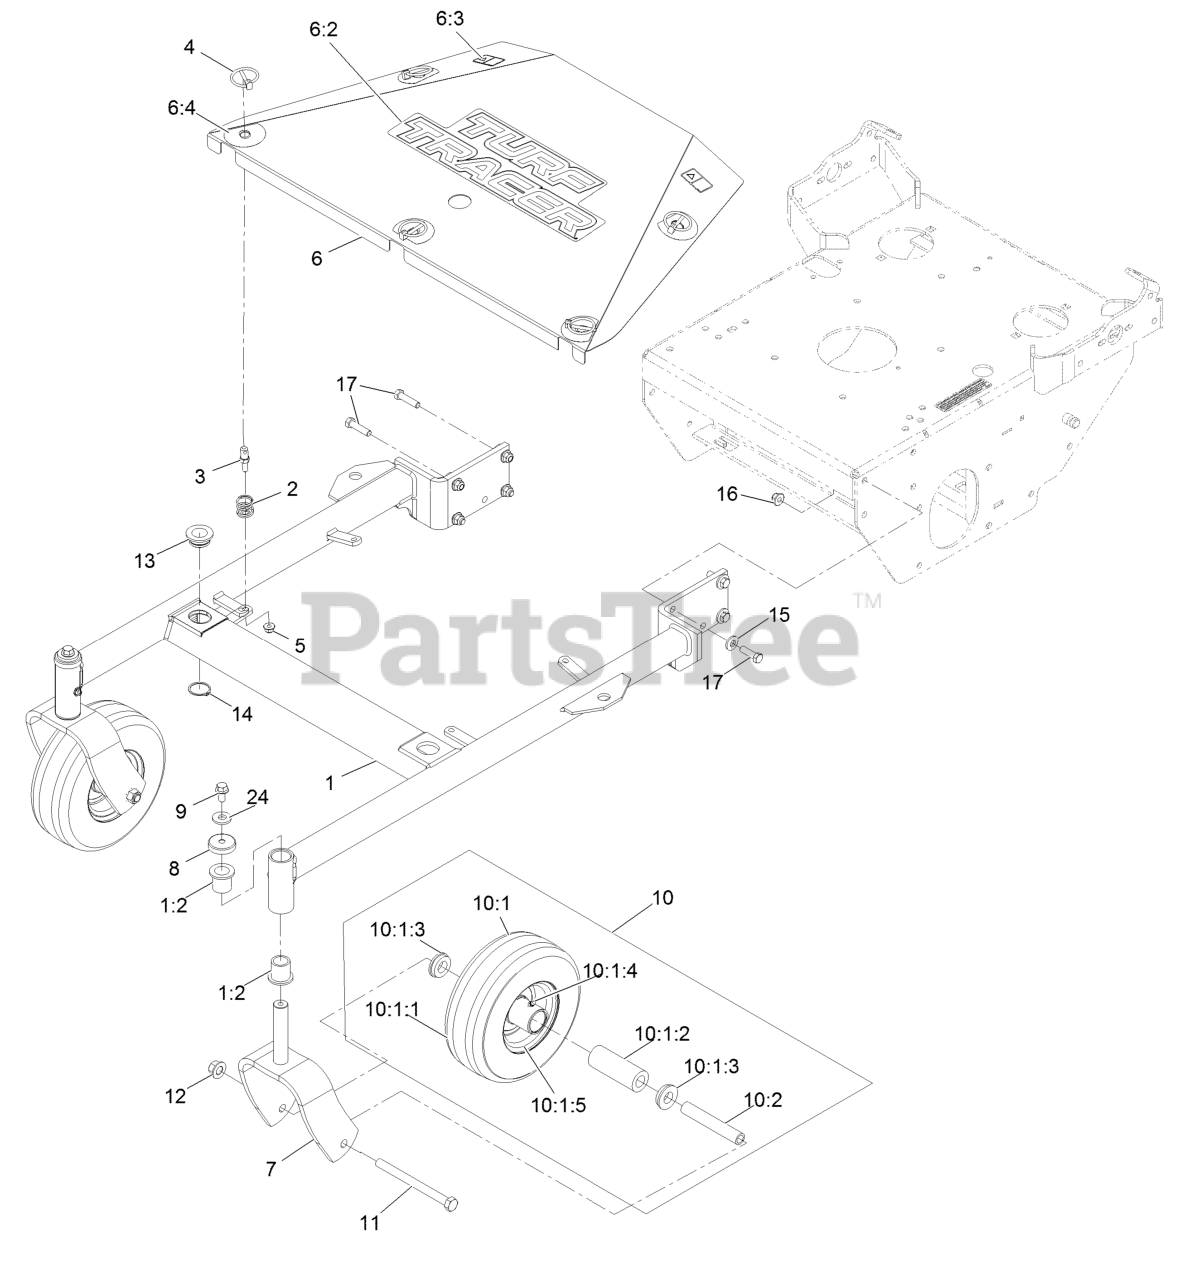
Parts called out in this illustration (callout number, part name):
1	ASM, FRAME W/ BUSHINGS, 3
1:2	BEARING-FLANGED
3	PIN-SPRING
4	PIN-LYNCH
5	NUT-HF, NI
6	ASM, SHIELD W/ DECALS, 36
6:2	DECAL-TURF TRACER
6:3	DECAL-WARNING
6:4	DECAL-SCRATCH COVER
7	FORK, CASTER
8	CAP, DUST
9	SCREW-HHF
10	KIT, SP CASTER WHEEL REPL
10:1	Wheel And Tire ASM
10:1:1	Tire
10:1:2	BEARING
10:1:3	BUSHING
10:1:4	FITTING-GREASE
10:1:5	Wheel
11	SCREW-HH
12	Nut-Lock 1/2-13
13	BUSHING-DECK
14	RING-RETAINING
15	WASHER-BELLEVILLE
16	NUT-HF, NI
17	SCREW-HH
